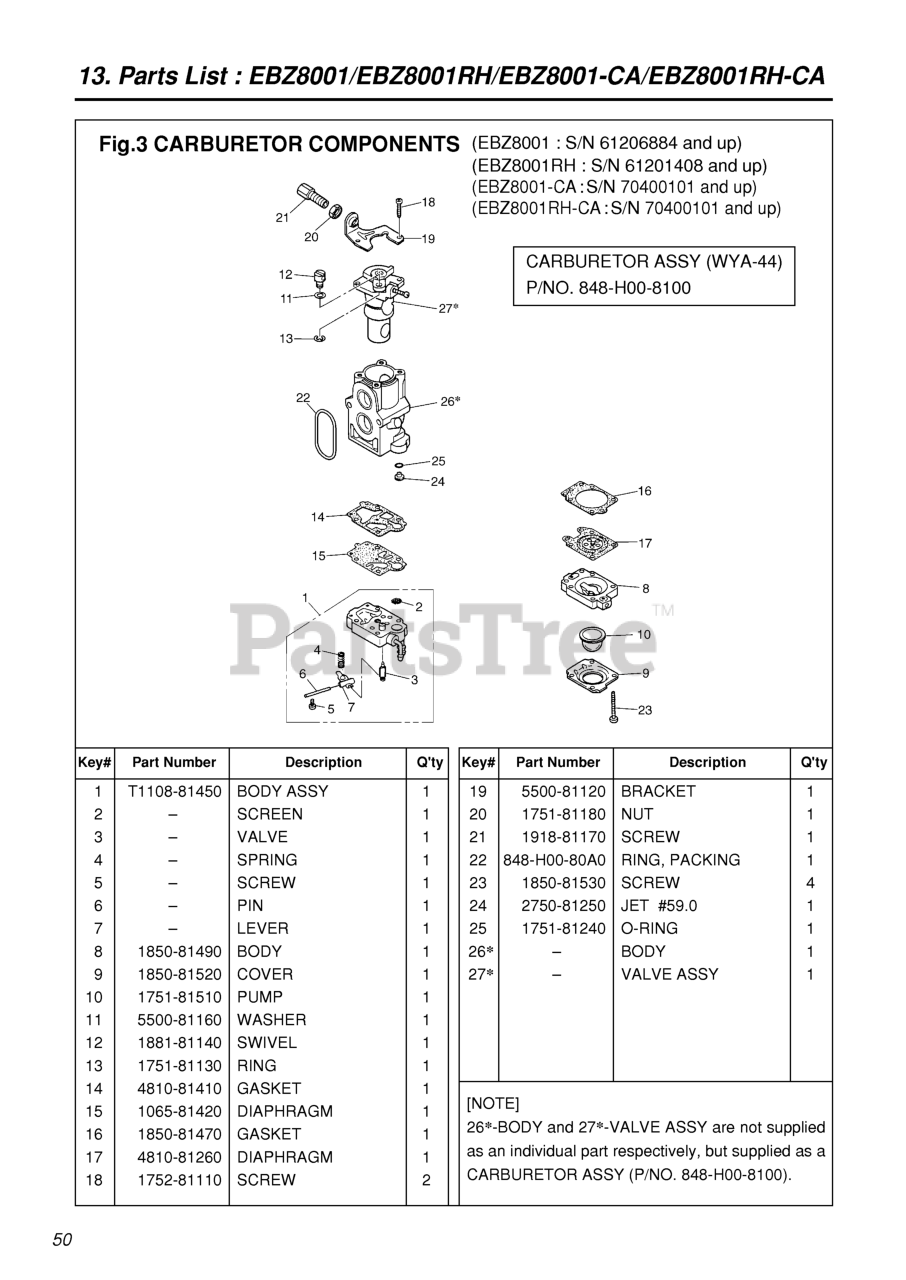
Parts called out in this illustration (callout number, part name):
1	BODY ASSY.
2	SCREEN
3	VALVE
4	SPRING
5	SCREW
6	PIN
7	LEVER
8	BODY, PURGE
9	COVER, PUMP
10	PUMP, PRIMING
11	WASHER
12	SWIVEL
13	RING
14	GASKET, PUMP
15	DIAPHRAGM
16	GASKET, DIAPHRAGM
17	DIAPHRAGM (RPLS 3310-81260)
18	SCREW
20	NUT, CABLE ADJUSTER
21	SCREW, CABLE ADJUSTER
22	RING, PACKING
23	SCREW
24	JET
25	RING, O
26	CARBURETOR-A (WYA-44)
27	CARBURETOR-A (WYA-44)
NI	CARBURETOR-A (WYA-44)
